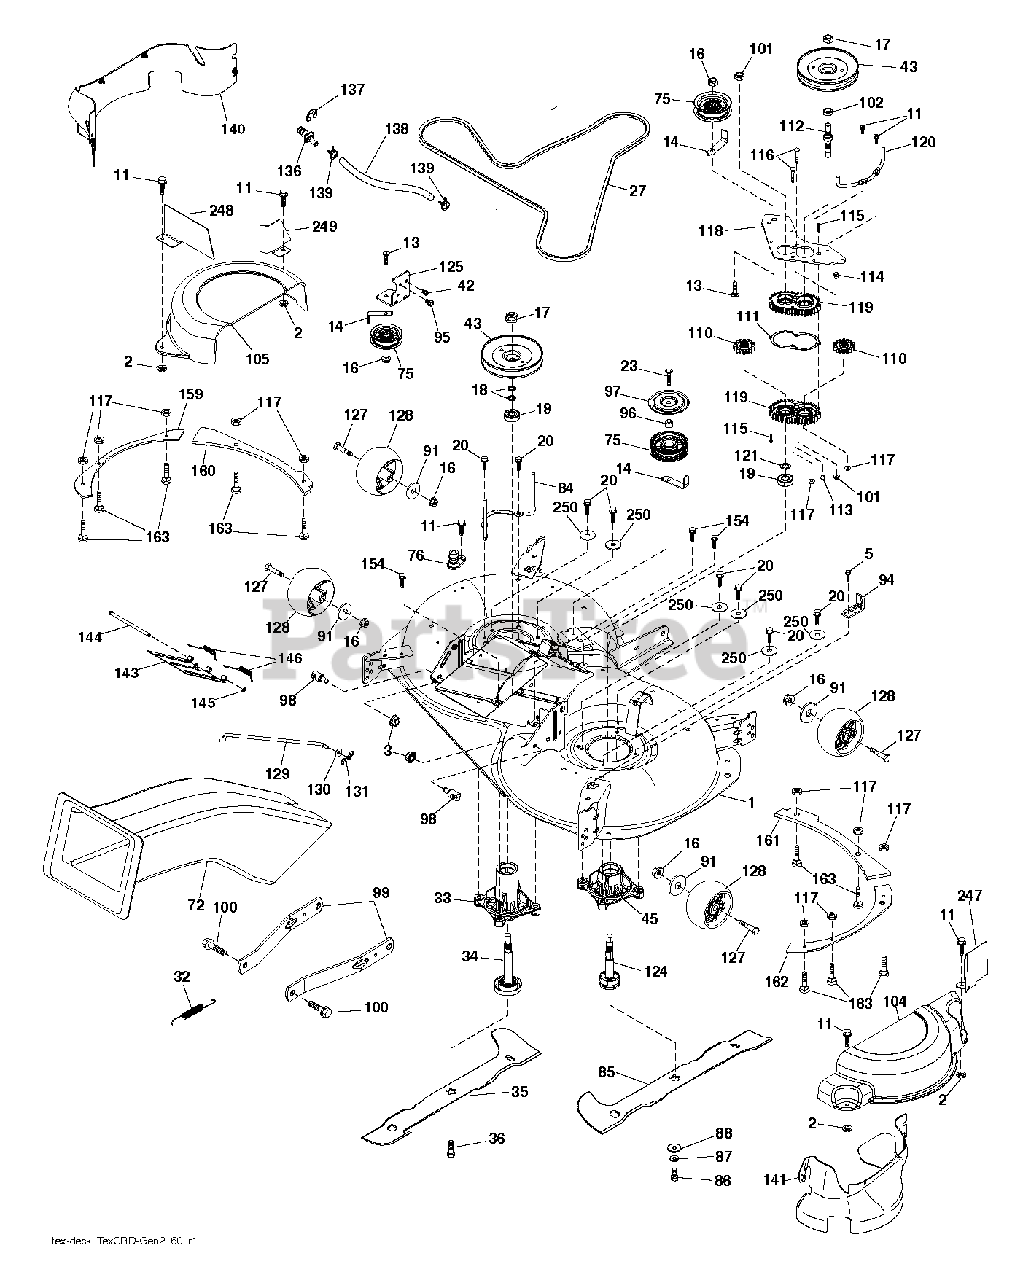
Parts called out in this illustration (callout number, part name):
1	DECK SVC 107HP.EZMUL.498
2	PALNUT 1/4
3	NUT LOCK HEX FLANGE 5/16-18
5	BOLT.5/16HEX.WHS.HD
11	SCREW.1/4-20X5/8
13	BOLT.3/8-16X1.50
14	KEEPER, BELT IDLER
16	NUT LOCK FLG 3/8-16 UNC
17	NUT.FLANGE.LOCK.TOP
18	WASHER.SPACER.MANDREL
20	SCREW, WASHER HEAD
23	SCREW LT
27	BELT BELT. ELECTRIC MOWER DRIV
32	SPRING 107CM & 97CM ELECTRIC D
33	HOUSING.MANDREL.REV.TALL.N/GRS
34	SHAFT ASM.REV.TALL.N/GREASEBL
35	BLADE.107.LH.SINGLE.NON.QD
36	BOLT.WASHER.ASM.7/16-2
42	SCREW
43	PULLEY PULLEY MANDREL 5.438 PD
45	RP HOUSING.MANDREL.REV.REVS.
71	SCREW 3/8-16X1/2
72	RB CHUTE 107/97 TEX GENII
75	FLAT IDLER PULLEY
76	1/2" BARB.DECK.WASHOUT.PORT
84	KEEPER KEEPER. LH MANDREL BELT
85	BLADE.107.RH.SINGLE.NON.QD
86	BOLT.3/8-24X1.25GR8. LHTHRD
87	LOCKWASHER
88	WASHER.BLADE
91	WASHER
94	BRKT.CLUTCH.CABLE
95	SCREW, 3/8-16X3/4
96	SPACER
97	PROTECTOR
98	STUD.FASTNER.W/ANTI-ROTATE
99	ARM.SUSPENSION.MOWER.R
100	BOLT.SHOULDER
101	NUT.CROWNLOCK.9/16 -18.UNC
102	SPACER BEARING
104	COVER.MANDREL.107.RH.GEN.2
105	COVER.MANDREL.107.LH.GEN.2
110	GEAR GEAR OUTPUT
111	GASKET GASKET GEARCASE
112	SHAFT SHAFT. CRD GEARCASE ADAP
113	PLUG PLUG OIL
114	VALVE VALVE RELIEF
115	SCREW
116	BOLT.CARIGE.SS.1/4-20X1.75GR5
117	NUT T
118	ARM ARM. CLUTCHING 107 TEX CRD
119	GEARCASE GEARCASE SUBASM
120	KEEPER KEEPER. RH MANDREL BELT
121	WASHER WASHER
124	SUB.ASM.REVERSE.THREAD.REV
125	BRACKET
127	BOLT.SHOULDER.3/8-16X3-5/8.
128	WHEEL. GUAGE RALLY
129	ROD ROD. SWAY CRD GEN II
130	WASHER
131	PIN.COTTER.5/16.BOW TI
136	PLUG WASHOUT PORT HOOKUP
138	107.WASHOUT.PORT.HOSE (2 2)
139	HOSE.3/8.CLAMP (2 2)
140	GUARD FRENCH 107 TEX ASSEMBLY
141	GUARD SUBASM. 107 TEX GEN 2 RH
143	COVER DOOR.107 CM CRD EZ MULCH
144	PIN PIN.HINGE
145	E-RING.5/16"
146	SPRING SPRING: EZ MULCH DOOR
154	SCREW T-30 1/4-20 X
159	REINFORCE.PLATE.LHS.BOLT.431
160	REINFORCE.PLATE.LH.FT.X431
161	REINFORCE.PLATE.RH.FRT.X431
162	REINFORCE.PLAT.RH.SD.BLT.X431
163	BOLT
247	GUARD.STEEL.CRD.MANDREL.COV.FR
248	GUARD.STEEL.CRD.MANDREL.COV.FR
249	GUARD.STEEL.CRD.MANDREL.COV.FR
